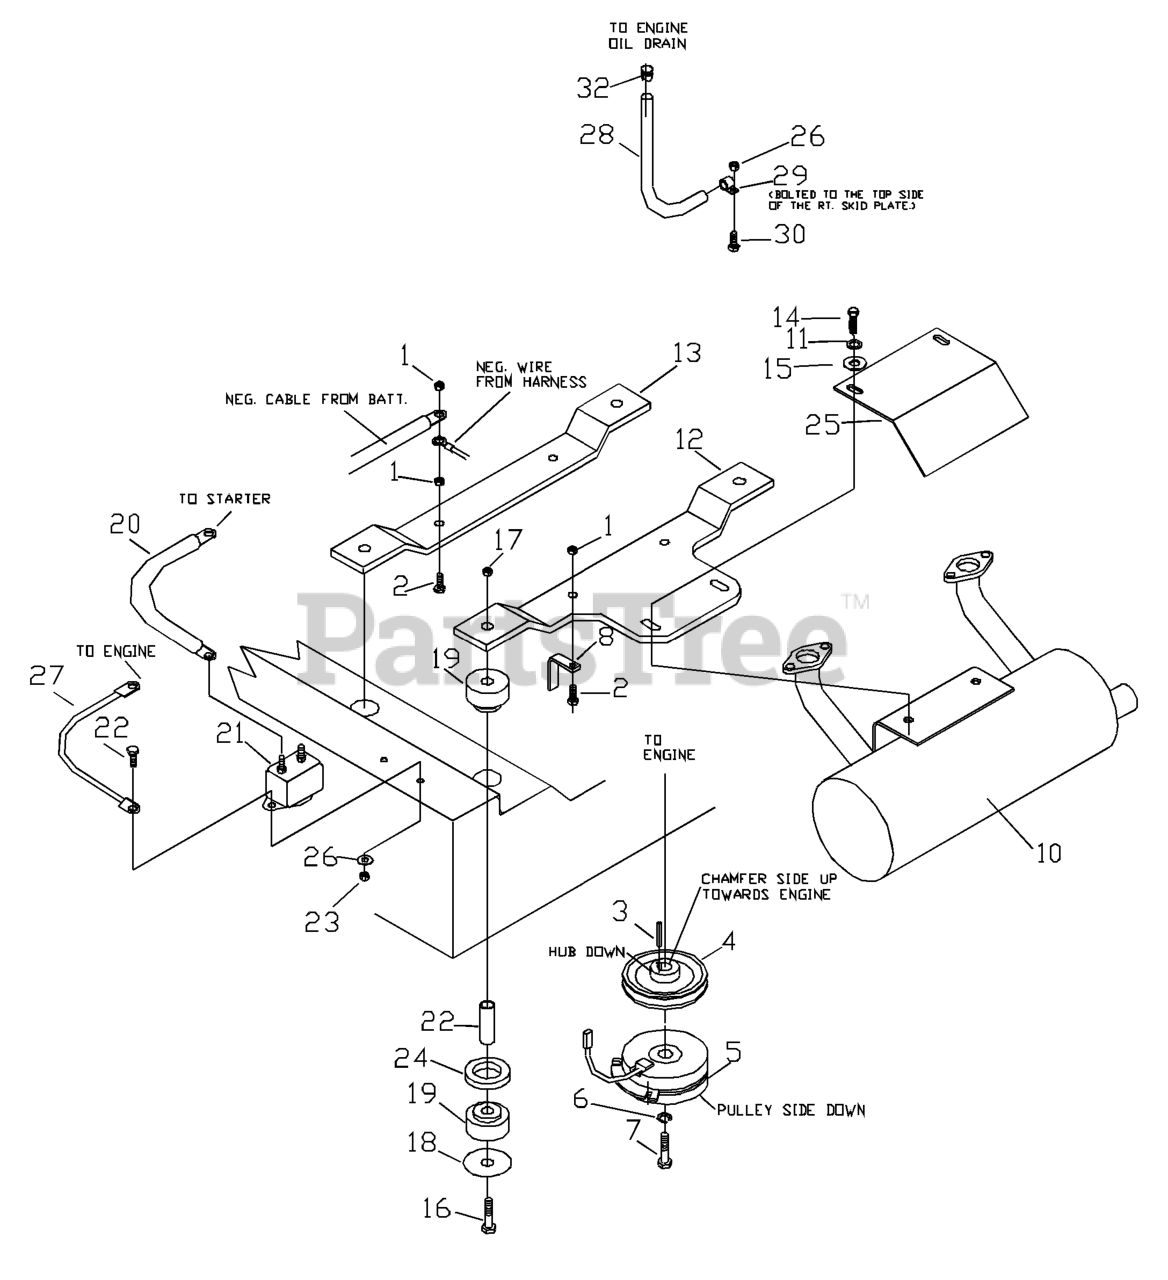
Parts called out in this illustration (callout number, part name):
1	NUT 5/16C CENTERLOCK
2	HCS 5/16C X 1 3/4
3	KEY 1/4" SQ X 1 7/8"
5	ELECTRIC CLUTCH W/CABLE
6	WASHER 7/16 LOCK
7	BOLT 7/16F X 2 1/2
8	CLUTCH TIE DOWN
9	KAW PIGTAIL
10	MUFFLER KAWASAKI GEN II
11	WASHER.LOCK.HVY.HLCL.SPR.5/16
12	REAR ENGINE MOUNT
13	ENGINE MOUNT
14	HCS 5/16C X 3/4
15	WASHER 5/16 FLAT
16	HCS 1/2C X 3 1/4
17	NUT 1/2-13 HEX NYLOC ZD
18	ISOLATOR WASHER
20	CABLE POSITIVE
22	HCS 1/4C X 5/8
23	NUT 1/4C CENTER LOCK
24	ISOLATOR SPACER
25	MUFFLER GUARD
26	WASHER 1/4 INT TOOTH
27	GROUND WIRE (KAW)
28	OIL DRAIN HOSE (KAW)
30	HCS 1/4C X 3/4 HCS
